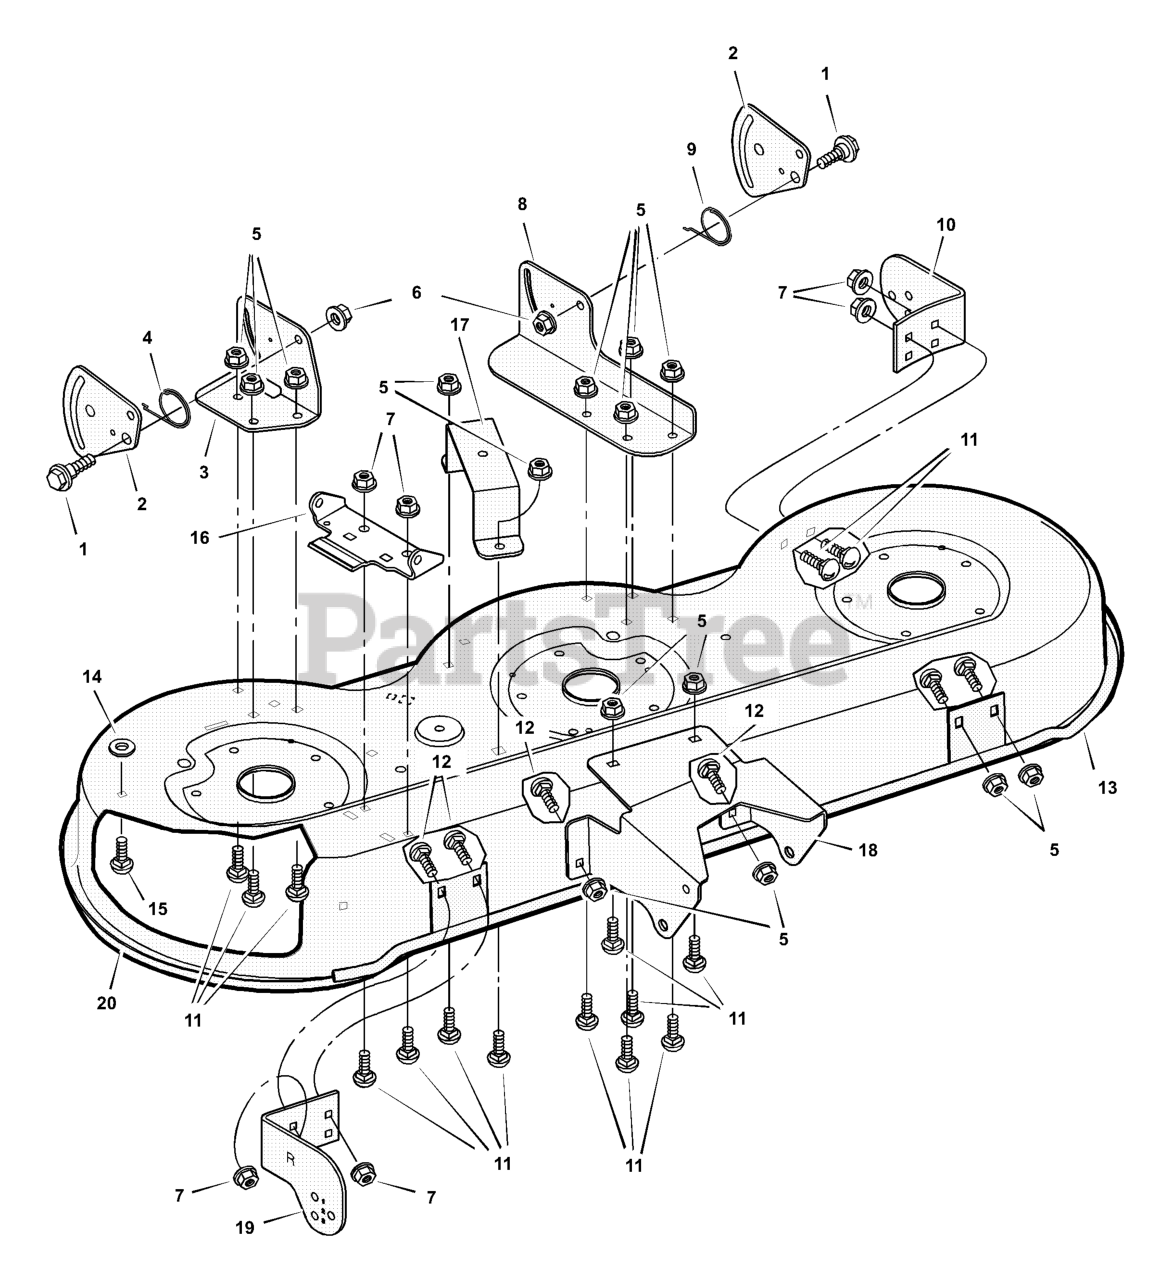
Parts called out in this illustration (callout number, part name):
1	Bolt, Shoulder
2	Plate, Suspension
3	Bracket, Right Rear
5	Nut, Flange
6	Nut, Flange
7	Nut, Flange
8	Bracket, Left Lifter
10	Bracket, Left Gage Wheel
11	Bolt, Carriage
12	Bolt, Carriage
13	Assembly, Reinforcement
14	Retainer, Push
15	Bolt, Carriage
16	Bracket, Hinge
17	Bracket, Bell Crank
18	Bracket, Front Deck
19	Bracket, Right Gage Wheel
20	Housing, 46" Blade
